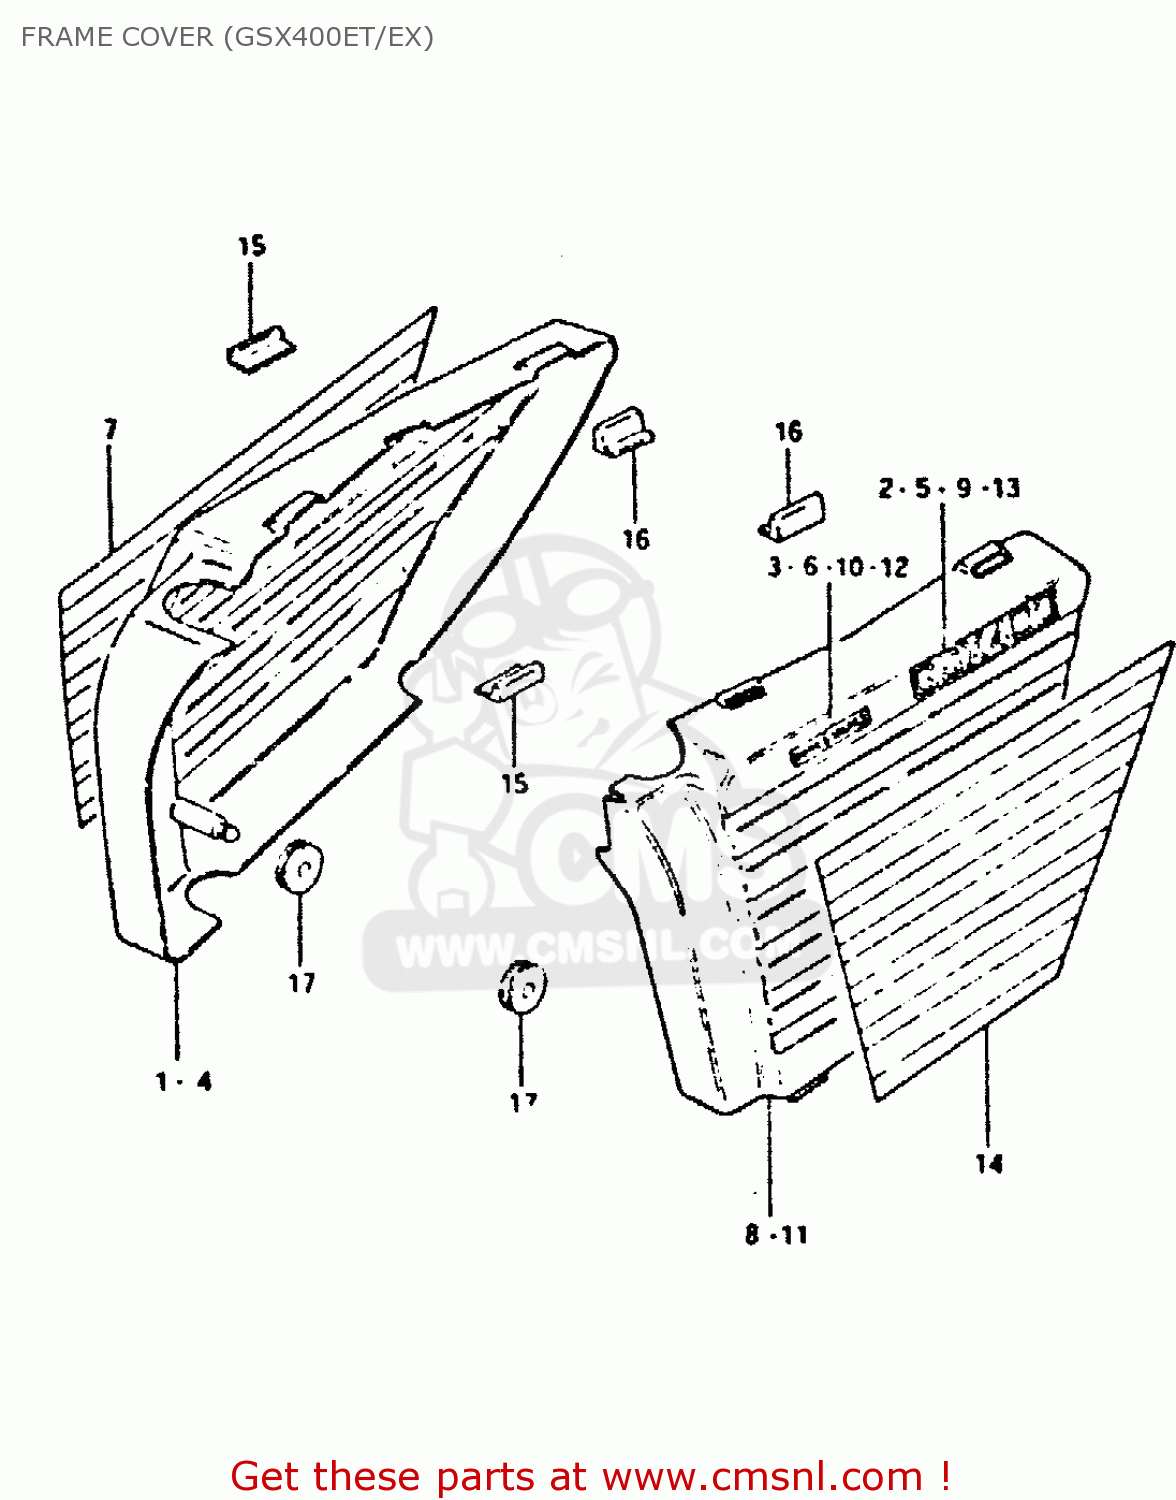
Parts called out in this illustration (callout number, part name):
1	COVER,FRAME,RIGHT
2	EMBLEM, "GSX400" (WHITE)
3	EMBLEM (WHITE)
4	COVER,FRAME,RIGHT
5	EMBLEM, "GSX400" (BLACK)
6	EMBLEM (BLACK)
7	TAPE SET, RH
8	COVER,FRAME,LEFT
9	EMBLEM, "GSX400" (WHITE)
10	EMBLEM (WHITE)
11	COVER,FRAME,LEFT
12	EMBLEM, "GSX400" (BLACK)
13	EMBLEM (BLACK)
14	TAPE SET
15	CUSHION,FRAME COVER
16	CUSHION,FRAME COVER
17	CUSHION
